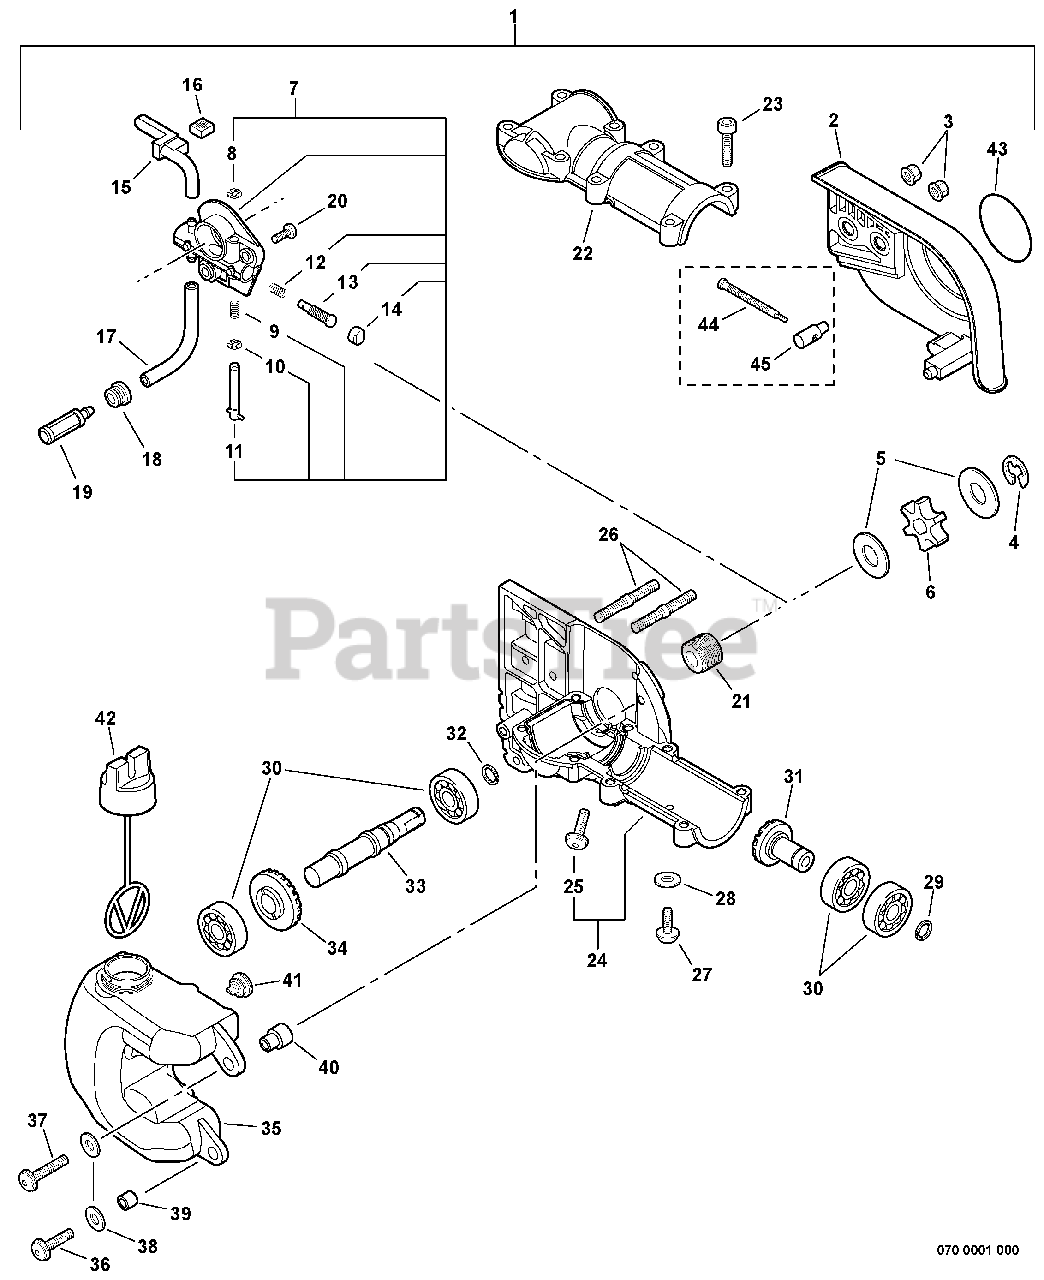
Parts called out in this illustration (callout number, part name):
1	AUTO OILER/GEAR CASE ASSY
2	GUARD, SPROCKET
3	NUT - 6 -- FLANGE
4	RING, RETAINING
6	SPROCKET, DRIVE
7	AUTO-OILER ASSY
8	RING, RETAINING
11	NEEDLE, ADJUST
12	SPRING, PLUNGER
13	PLUNGER ASSY
14	CAP, OIL PUMP
15	PIPE, OIL OUTLET
16	PAD, FOAM
17	PIPE - 3X6X75 -- BLACK
18	GROMMET
19	FILTER, OIL
20	SCREW - 5X10
21	GEAR - WORM
22	CASE, GEAR - UPPER
23	SCREW - 5X25
24	CASE, GEAR - LOWER
25	SCREW - 5X10
26	STUD - 6
27	SCREW - 5X10
28	WASHER - 5
29	RING, RETAINING - 12
30	BEARING, BALL - 6001
31	GEAR - BEVEL
32	RING, RETAINING - 12
33	GEAR - SHAFT
34	GEAR - BEVEL
35	TANK, OIL
36	SCREW - 5X16
37	SCREW - 5X25
38	WASHER - 5
42	CAP ASSY
43	LABEL - ECHO
44	SCREW, TENSIONER
45	TENSIONER, CHAIN
